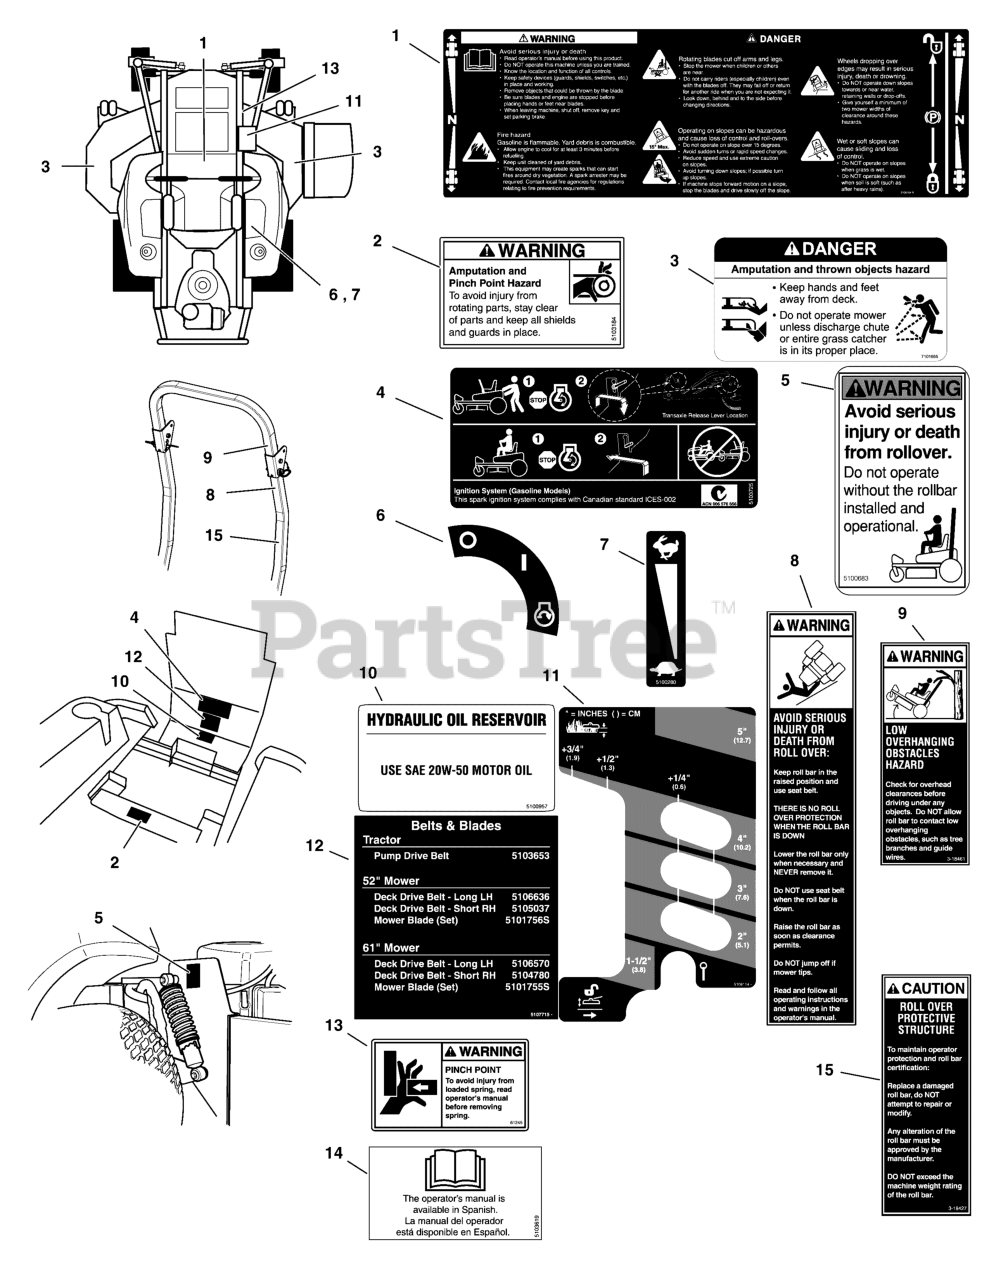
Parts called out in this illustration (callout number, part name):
1	DECAL, MAIN SAFETY
2	DECAL, WARNING, HAND IN BELT, ENG ONLY
3	DECAL, DANGER DO NOT OPERATE W/O DEFLECT
4	DECAL, TRANSAXLE RELEASE, 600/700
5	DECAL, Warning, ROLL BAR
6	DECAL, IGNITION CONTROL
7	DECAL, Throttle Control
8	DECAL, WARNING, FOLDING ROLL BAR
9	DECAL, WARNING OVERHANG, ROPS (SV)
10	DECAL, HYDRAULIC OIL, SAE 20W50
11	DECAL, CUTTING HEIGHT
12	DECAL, BELT & BLADE, ISX800Z, 2 BELT
13	DECAL, Pinch Point
14	DECAL, MANUAL AVAILABLE IN SPANISH
15	DECAL, CAUTION, FOLDING ROLL BAR
